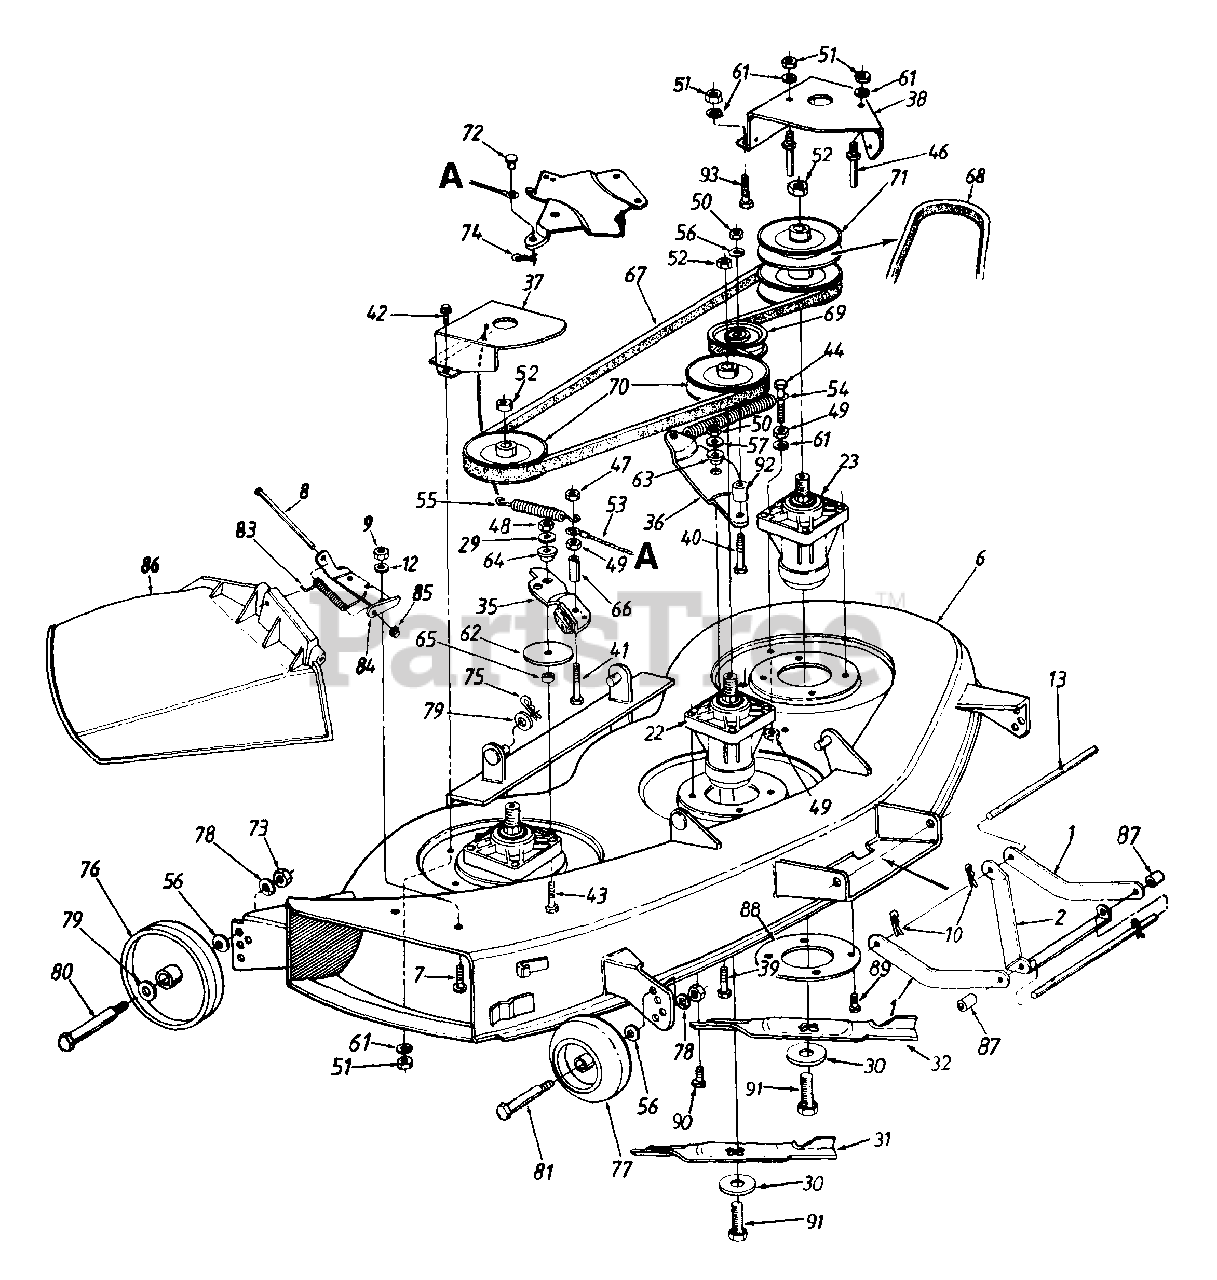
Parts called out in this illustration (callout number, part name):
8	Hinge Pin
9	Hex Nut 1/4-20 Thd.
12	Bell-Wash. 1/4" I.D.
13	Deck Connecting Rod
22	Spindle Ass'y. (R.H. & Center)
23	Spindle Ass'y. (L.H.)
29	Lock Wash. 5/16" I.D.
30	Bell-Wash. .47" I.D. x 1.5"
31	High Lift Blade 14.88" Lg. (Middle)
32	High Lift Blade 16.28" Lg. (R.H. & L.H.)
35	Deck Brake Brkt. Ass'y.
36	Idler Bracket
39	Hex Bolt 3/8-24 x 1.0" Lg.
40	Hex Bolt 3/8-24 x 2" Lg.
41	Hex Bolt 1/4-28 x 1.75" Lg.
42	Hex Wash. Hd. Tap-Scr. 1/4-20 x .5" Lg.
43	Hex Bolt 5/16-24 x 1.5" Lg. (Grade 5)
44	Hex Bolt 1/4-28 x 1.5" Lg.
46	Belt Guard Pin 1/4" Dia.
47	Hex Cent. L-Nut 1/4-28 Thd.
48	Hex Nut 5/16-24 Thd.
49	Hex Nut 1/4-28 Thd.
50	Hex Nut 3/8-24 Thd.
51	Hex Nut 1/4-20 Thd.
52	Hex Flange L-Nut 5/16-18 Thd.
53	Brake Cable Ass'y.
54	Extension Spring 6.17" Lg.
55	Extension Spring 3.97" Lg.
56	Bell-Wash. .38" I.D. x .88" O.D.
57	Bell-Wash. .39" I.D. x 1.13" O.D.
61	L-Wash. 1/4" I.D.
62	Fl-Wash. 5/16" I.D. x 3" O.D.
63	Shld. Spacer .625" I.D.
64	Shld. Spacer
65	Spacer .34" I.D.
66	Spacer .326" I.D
67	V-Belt
68	V-Belt
69	Fl-Idler Pulley 3.5" O.D.
70	Pulley 5.0" Dia.
71	Double Pulley 5.0" Dia.
72	Clevis Pin 1/4" Dia. x .53" Lg.
73	Hex Nut 3/8-16 Thd.
74	Intern. Cotter Pin 5/16" Dia.
75	Intern. Cotter Pin 3/8 Dia.
76	Deck Wheel 5" Dia.
77	Deck Wheel w/Insert 5" Dia.
78	L-Wash. 3" I.D.
79	Fl-Wash. .531" I.D.
80	Shoulder Bolt .498" Dia. x 1.64" Lg.
81	Shoulder Bolt
83	Torsion Spring
84	Hinge Mtg. Brkt.
86	Chute Ass'y. Comp.
87	Spacer 5/8" I.D. x 7/8" O.D.
90	Hex Wash. Hd. Scr. 5/16-18 x .75" Lg.
91	Hex L-Bolt 7/16-20 x 1" Lg.
92	Spacer .38" I.D.
93	Hex Bolt 1/4-20 x .5" Lg.
17258A-0648	Deck Belt Cover, 46" Black - TECH GRAY (0648)
17258A-0665	COVER:BELT:DECK 46 - YARDMAN GREEN (0665)
